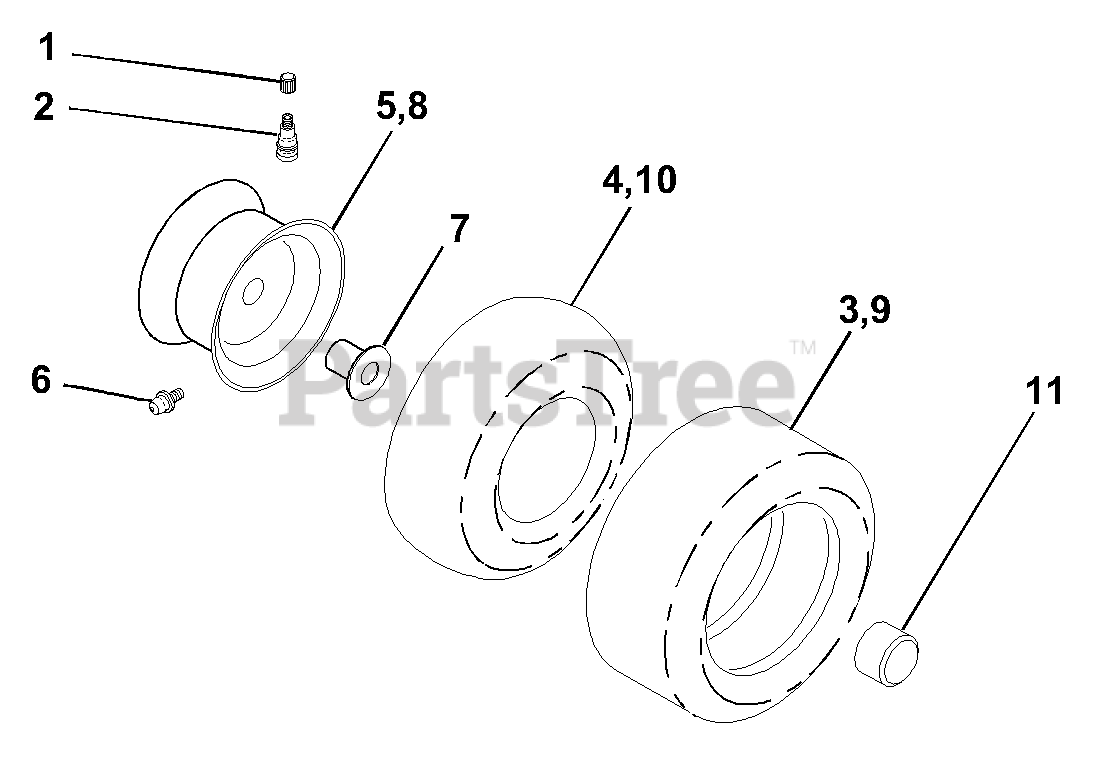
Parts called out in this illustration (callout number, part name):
1	Cap, Tire valve
2	Stem, Valve
3	Tire, Front
4	Tube, Front
5	Rim assembly, 6" front
6	Fitting, Grease
7	Bearing, Flange
8	Rim assembly, 8" rear
9	Tire, Rear
10	Tube, Rear
11	Cap, Hub Axle
